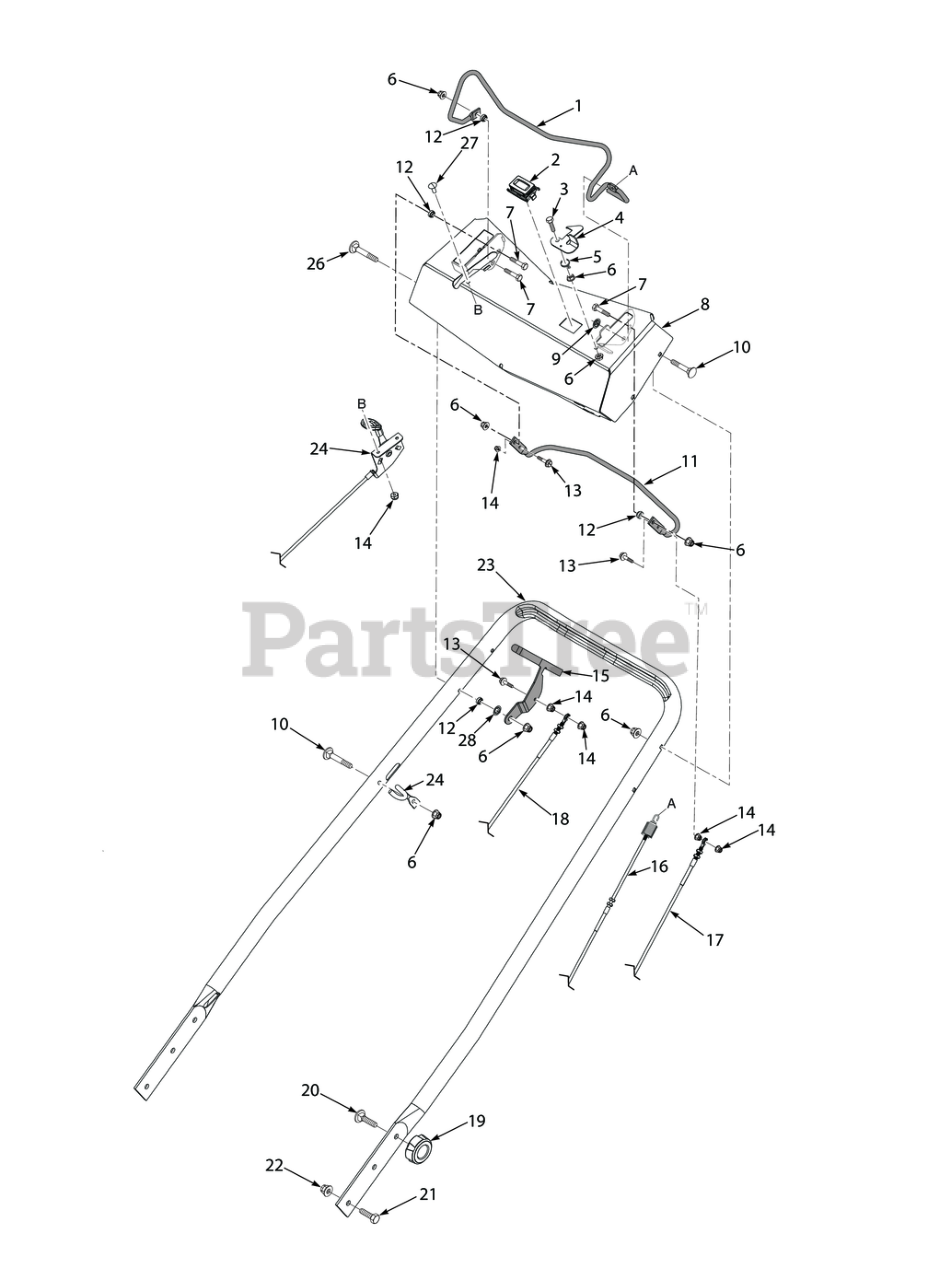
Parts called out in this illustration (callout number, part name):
1	Control, Deck
2	Hourmeter
3	Capscrew, Hex Head 1/4-20 x 1"
4	Latch, PTO
5	Spring, Hood Latch
6	Nut, Flanged Elastic Stop 1/4-20
7	BOLT, HEX HEAD, 1/4-20 X 3/4 GR.5
8	Instrument Panel w/Decal
9	Nut, Push-On 5/16-18
10	Bolt, Carriage 1/4-20 x 2"
11	Control, Drive
12	Pivot
13	Screw, #10-24 x 1" HD Slotted
14	Nut, Elastic Stop #10-24
15	Bracket, Brake Handle
16	Cable, Deck
17	Cable, Drive
18	Cable, Brake
19	Knob, 3/8-16 x 2.48 OD
20	Bolt, Carriage 3/8-16 x 3/4"
21	Screw, 3/8-16 x 3/4"
22	Nut, Flange Elastic Stop Nut, 3/8-16
23	Handle
24	Cable, Throttle
25	Guide, Pull Rope
26	Bolt, Carriage 1/4-20 x 2-1/2" Full Thread
27	Bolt, Carriage #10-24 x 1/2"
28	Washer, Curved
